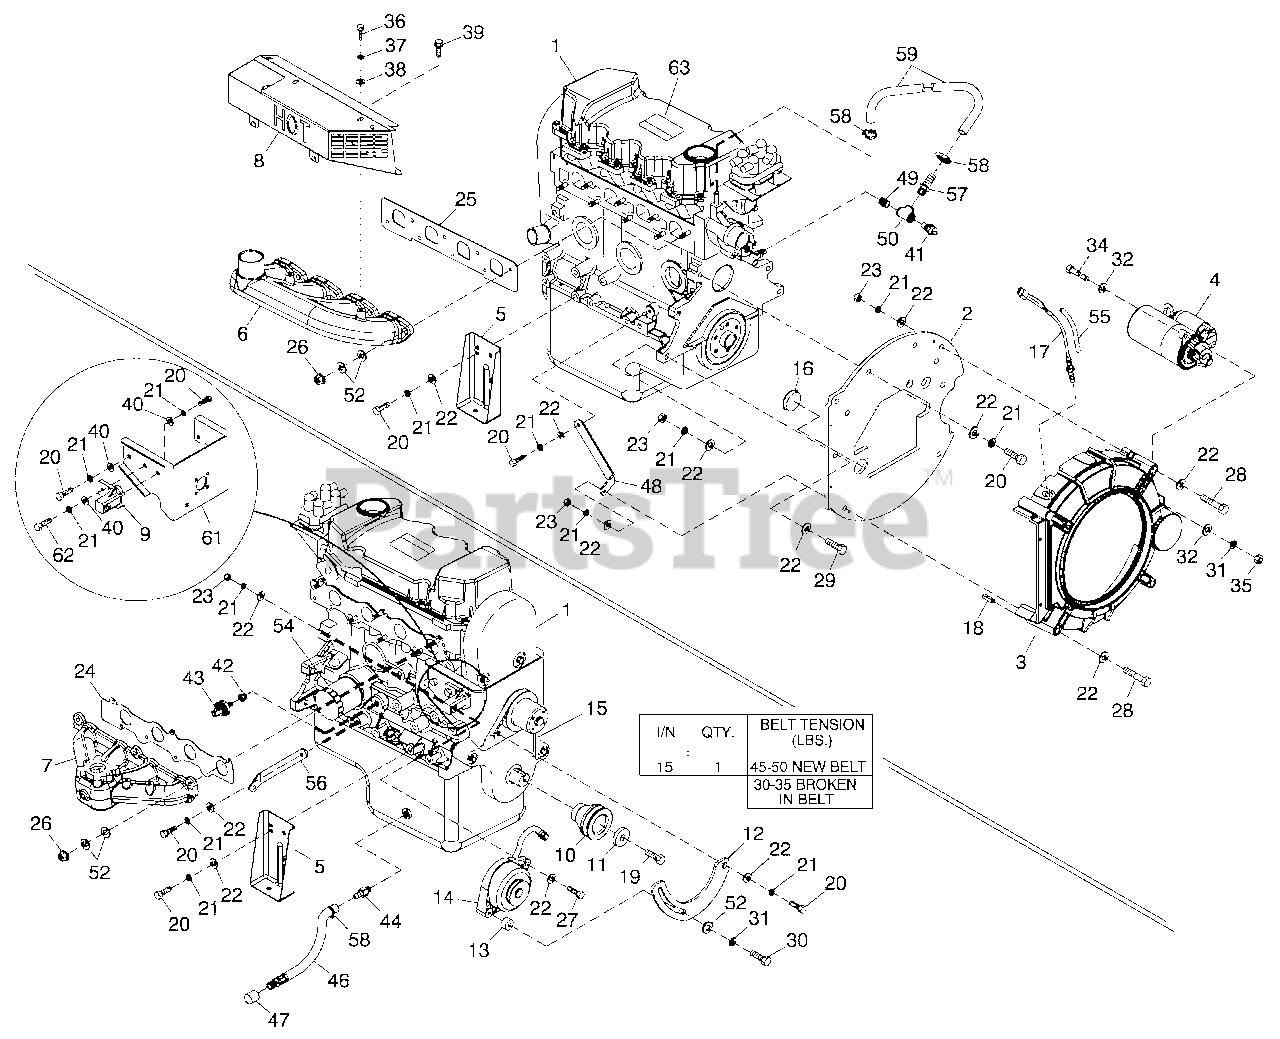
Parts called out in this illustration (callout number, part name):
1	ENGINE GENERAC 1.6L G11 CERT
2	ENGINE PLATE 1.6L (TO BE USED WITH PLATE SPACER P/N 0G2070.)
3	HOUSING BLOWER MACHINED 1.6L
4	STARTER MOTOR 12V
5	ENGINE M OUNTING FOOT STAMPING
6	EXHAUST MANIFOLD 1.6L MACHINED
7	INTAKE MANIFOLD MACHINED 1.6L
8	SHIELD 1.6L EXHAUST HEAT
9	DC ALTERNATOR ADAPTER MACHINED
10	PULLEY CRANKSHAFT MACHINED (3600RP M)
11	WASHER PULLEY
12	BRACKET TENSIONER DC ALT
13	SPACER ALTERNATOR
14	DC ALTERNATR HAN-KOK
15	V-BELT 3/8 X 30.6 (3600RP M)
16	CAP, 1.5" HOLE SHALLOW
17	ASSY MAGPICKUP (3/8-24 MALE)
18	PIN SPRING 1/4 X 3/4
19	SCREW HHC M12-1.5 X 40 G10.9
20	SCREW HHC M10-1.5 X 25 G10.9
21	WASHERLOCK M10
22	WASHER FLAT 3/8- M10ZINC
23	NUT HEX M10-1.5 CLASS 10 ZINC
24	GASKET INTAKE MANIFOLD 1.6L
25	GASKET EXHAUST MANIFOLD 1.6L
26	NUT TOP LOCK FL M8-1.25
27	SCREW HHC M10-1.5X 70 G8.8
28	SCREW HHC M10-1.5X 110 G10.9
29	SCREW HHC M10-1.5 X 40 G10.9
30	SCREW HHC M8-1.25X 35 G8.8
31	WASHERLOCK M8-5/16
32	WASHER FLAT 5/16- M8ZINC
33	TIE WRAP UL 7.4" X .19" BLK
34	SCREW HHC M8-1.25 X 40 G8.8
35	NUT HEX M8-1.25 G8 CLEAR ZINC
36	SCREW HHC 1/4-20 X 1/2 G5
37	WASHERLOCK M6-1/4
38	WASHER FLAT 1/4- M6 ZINC
39	SCREW HHTT M6-1.0 X 12 ZINC
40	WASHER FLAT M10 HEAVY DUTY
41	SWITCH HI-TE MP 245 D X 3/8 NPT
42	BSHG RDCR HEX 1/4 TO 1/8
43	SWITCH OIL PRESSURE 10PSI 2POL
44	ADAPTER DRAIN OIL
46	HOSE OIL DRAIN ASSY 21"
47	CAP HEX 1/4 NPT BRASS
48	STRUT LH 1.6L ENG ADAPT PLATE
49	NIPPLE PIPE 3/8 NPT X 1-1/2
50	PIPE TEE 3/8 NPT
51	SCREW HWHTF M6-1.0X16
52	WASHER FLAT .34 ID X .75 OD
54	OIL FILTER 1.6L
55	CONDUIT FLEX .25"ID (6" LG)
56	STRUT RH 1.6L ENG ADAPT PLATE
57	BARBED STR 3/8 NPT X 3/8
58	CLAMP HOSE .38-.87
59	HOSE COOLANT 3/8 ID 20R3 (11" LG)
61	BRACKET FAN ALT ADAPTER 1.6L
62	SCREW HHC M10-1.5X 35 G8.8
63	DECAL E MISSION CTRL INFO 1.6L
